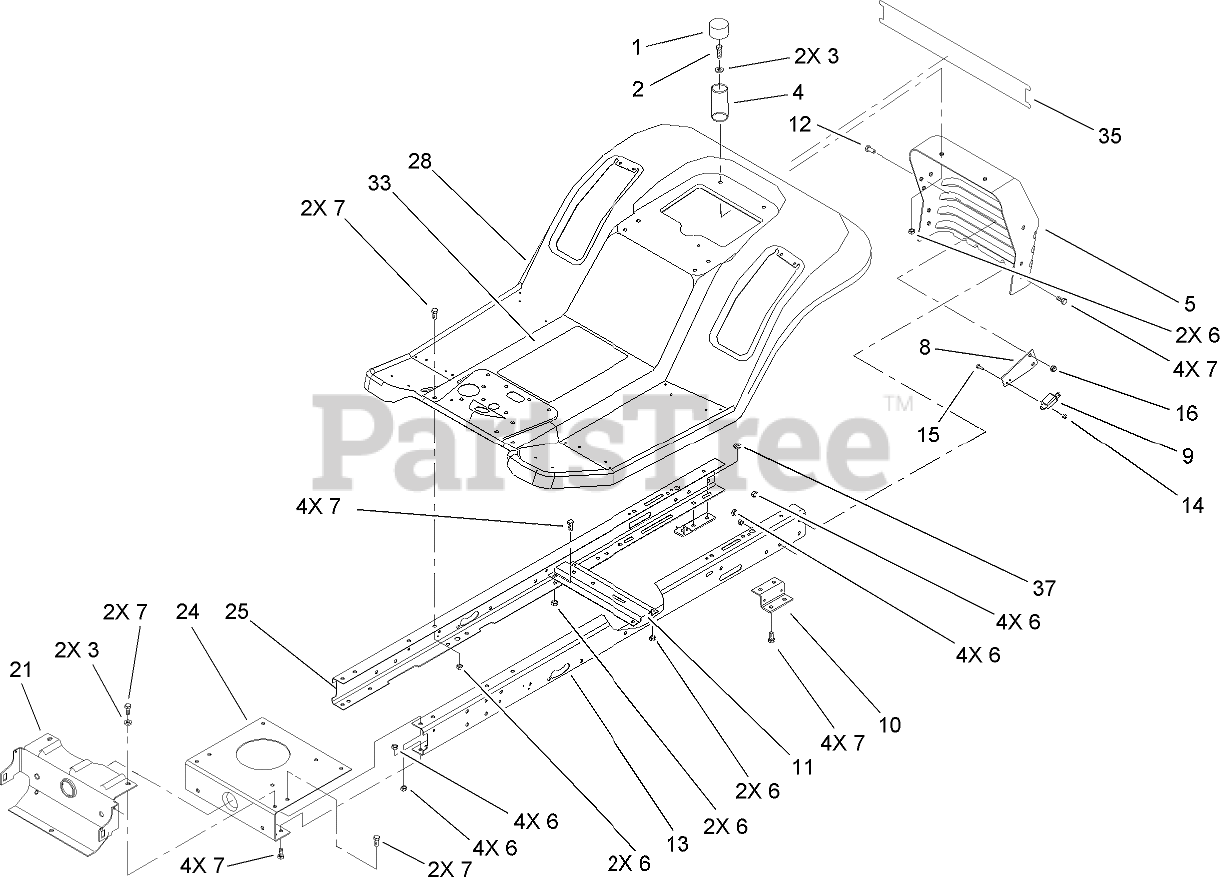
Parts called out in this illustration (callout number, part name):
1	CAP-PROTECTOR
2	SCREW-HH
3	WASHER-PLAIN
4	SPRING-COMPRESSION
5	SUPPORT-SEAT/REAR HITCH
6	NUT-LOCK, NI
7	SCREW-HH
8	PLATE-SWITCH
9	SWITCH-POLE, SINGLE
10	BRACKET-MOUNTING, TRANSMISSION
11	BRACKET-IDLER PIVOT
12	SCREW-HH
13	RAIL-FRAME, LH
14	NUT-LOCK
15	SCREW-SHH
16	NUT-LOCK, NI
21	SUPPORT-FRONT, AXLE
24	PLATE-MOUNTING, ENGINE
25	RAIL-FRAME, RH
28	REAR BODY ASM
33	DECAL-GEAR
35	DECAL-REAR FENDER, LAWN TRACTORS
37	WASHER-PLAIN
